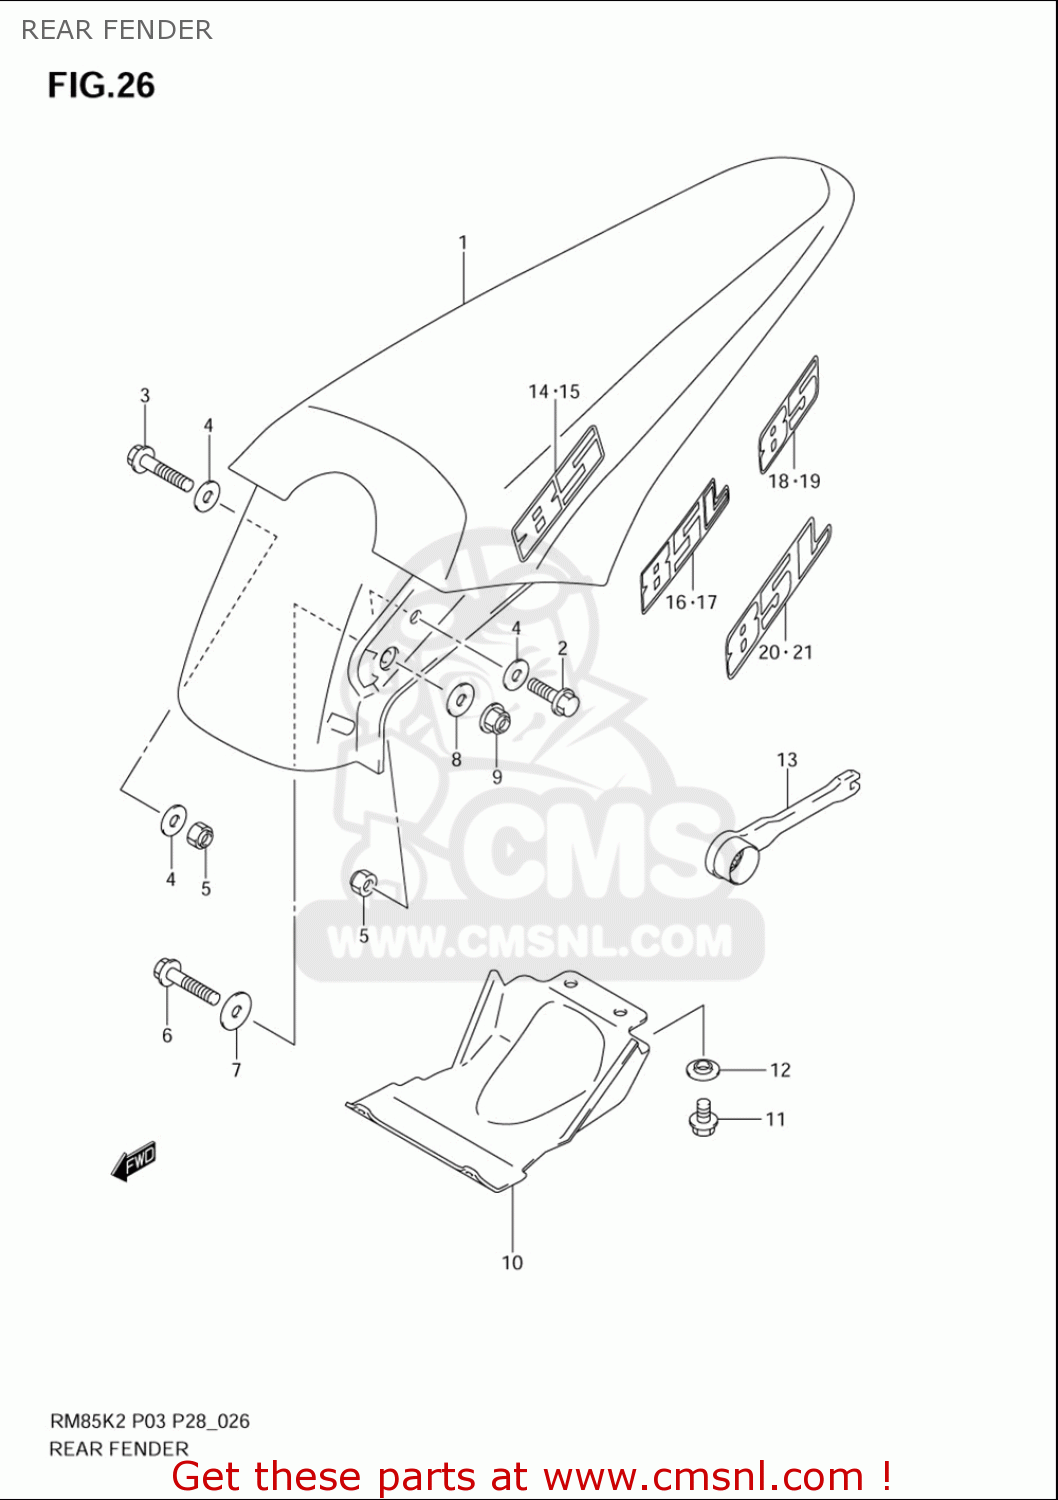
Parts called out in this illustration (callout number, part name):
1	FENDER,RR
2	BOLT,6X20
3	BOLT(6X30)
4	WASHER(6.5X20X1.2)
5	NUT 6MM
6	BOLT(6X30)
7	WASHER(6.5X26X2.3)
8	WASHER(6.5X18X1.6)
9	NUT
10	MUDGUARD,RR FENDER FR
11	BOLT
12	WASHER
13	SPARK PLUG WRENCH(21 & 5.8)
14	EMBLEM,RR FENDER,R
15	EMBLEM,RR FENDER,L
16	EMBLEM,RR FENDER,R
17	EMBLEM,RR FENDER,L
18	EMBLEM,RR FENDER,R
19	EMBLEM,RR FENDER,L
20	EMBLEM,RR FENDER,R
21	EMBLEM,RR FENDER,L
